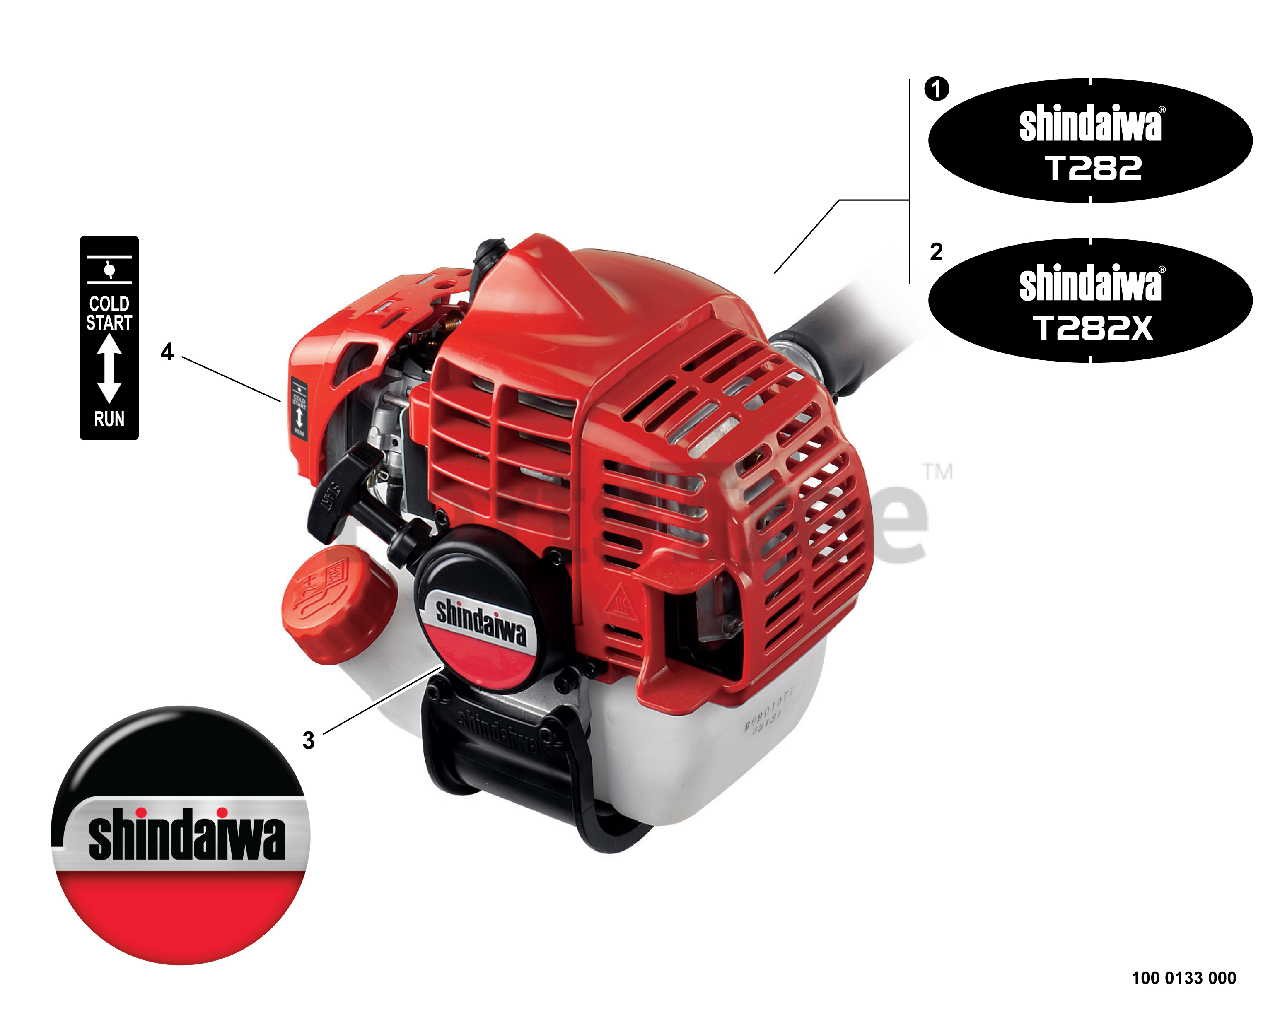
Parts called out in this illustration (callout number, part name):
1	LABEL - MODEL T282
2	LABEL - MODEL T282X
3	LABEL - SHINDAIWA
4	LABEL - CHOKE
